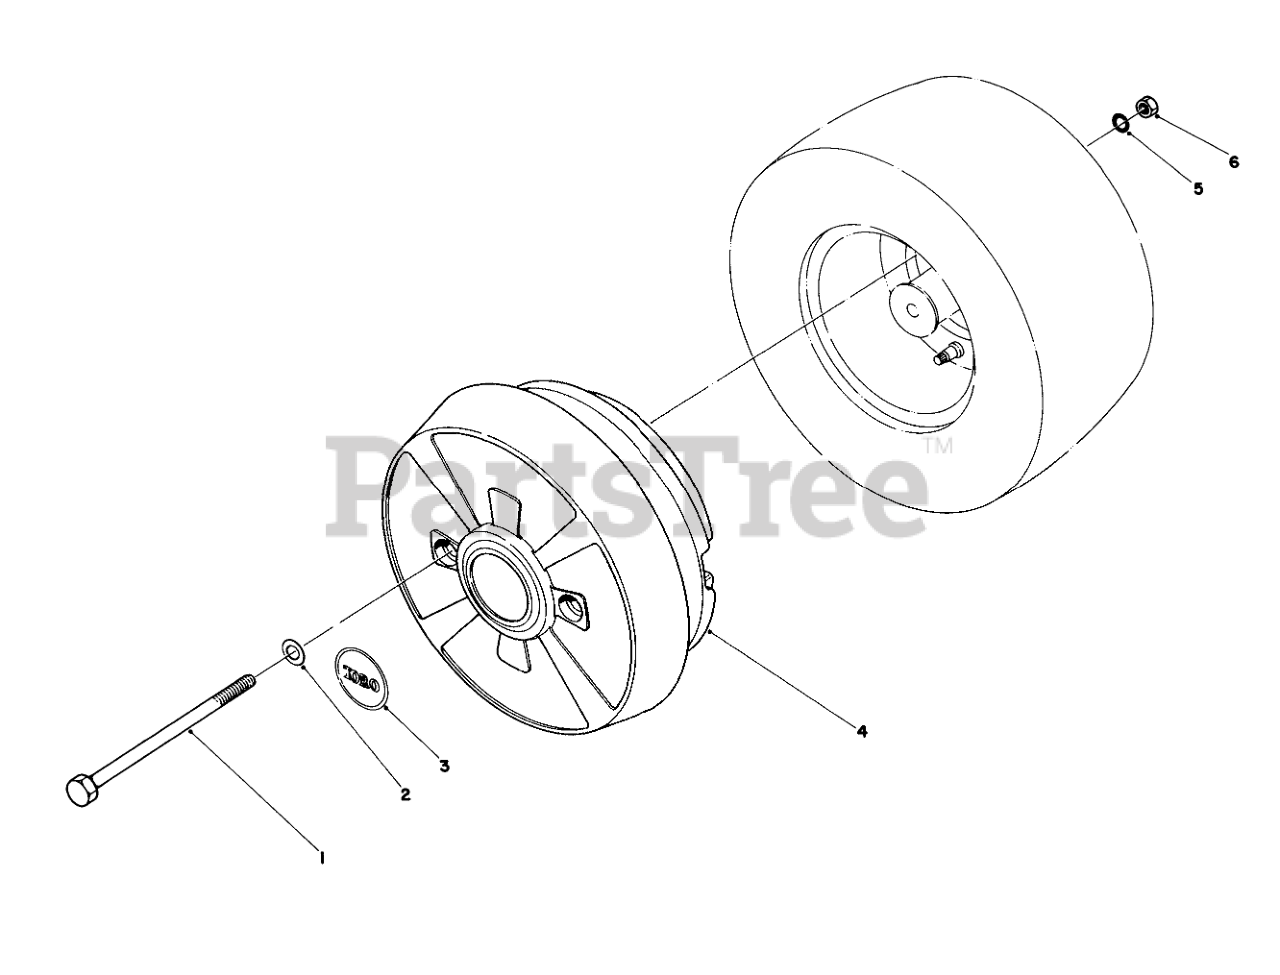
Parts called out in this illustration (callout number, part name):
1	SCREW-HH
2	WASHER-FLAT
3	Decal
4	WHEEL WEIGHT
5	WASHER-LOCK
6	NUT-HEX
